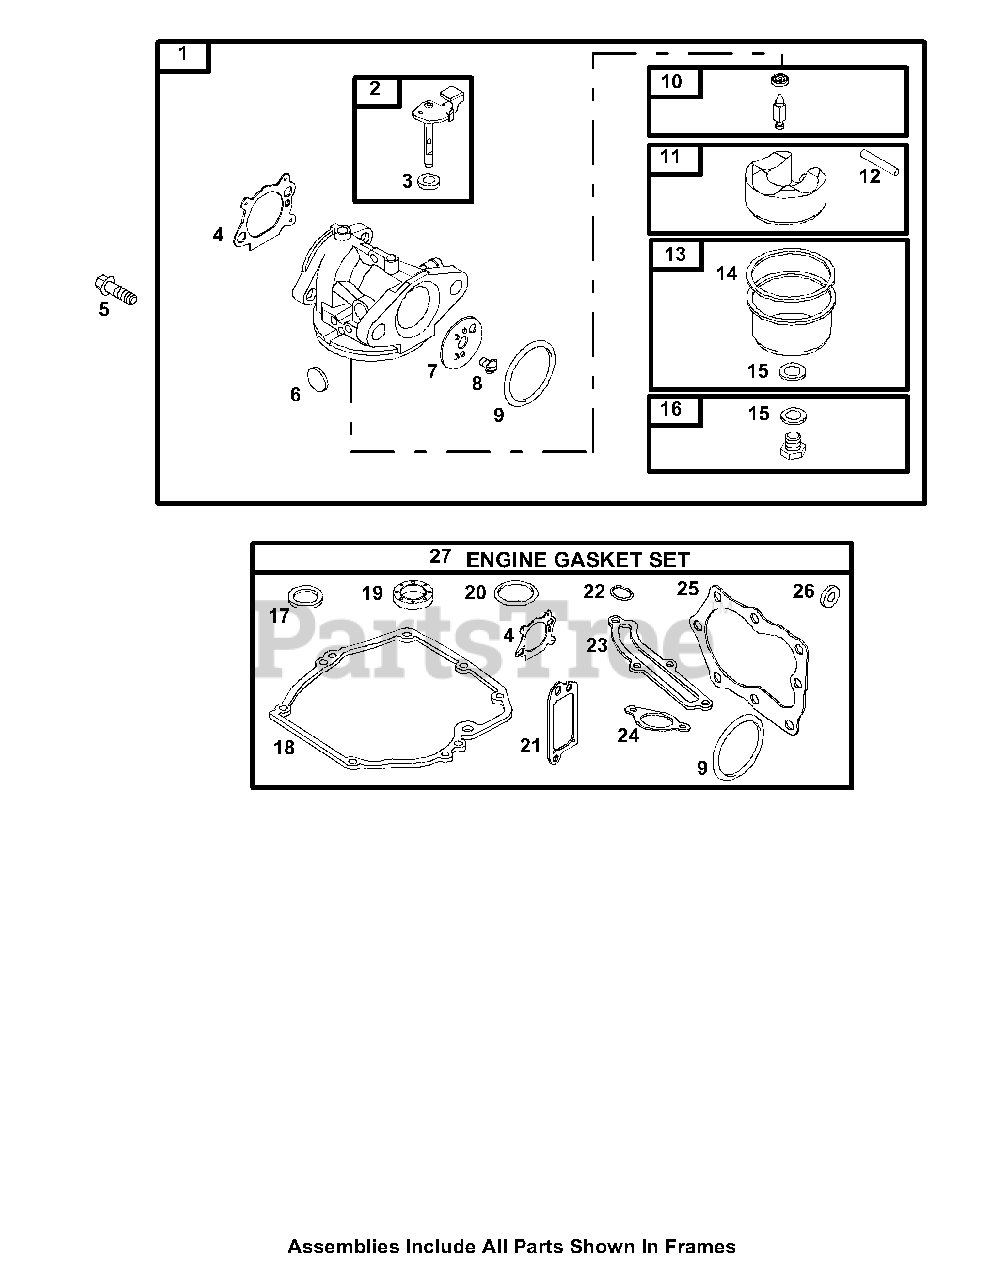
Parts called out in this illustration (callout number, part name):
1	Carburetor
2	Throttle Shaft
3	Choke/Throttle Shaft Seal
4	Air Cleaner Gasket
5	Screw (Carburetor)
6	Welch Plug
7	Throttle Valve
8	Screw (Throttle Valve)
9	O-Ring Seal (Intake Manifold)
10	Needle/Seat Kit
11	Carburetor Float
12	Float Hinge Pin
13	Float Bowl
14	Float Bowl Gasket
15	Sealing Washer
17	Oil Seal (Magneto Side)
18	Crankcase Gasket
19	Oil Seal
20	O-Ring Seal (Dipstick Tube)
21	Breather Gasket
22	O-Ring Seal (Dipstick Tube)
23	Breather Passage Gasket
24	Intake Gasket
25	Cylinder Head Gasket
26	Spacer
27	Engine Gasket Set
